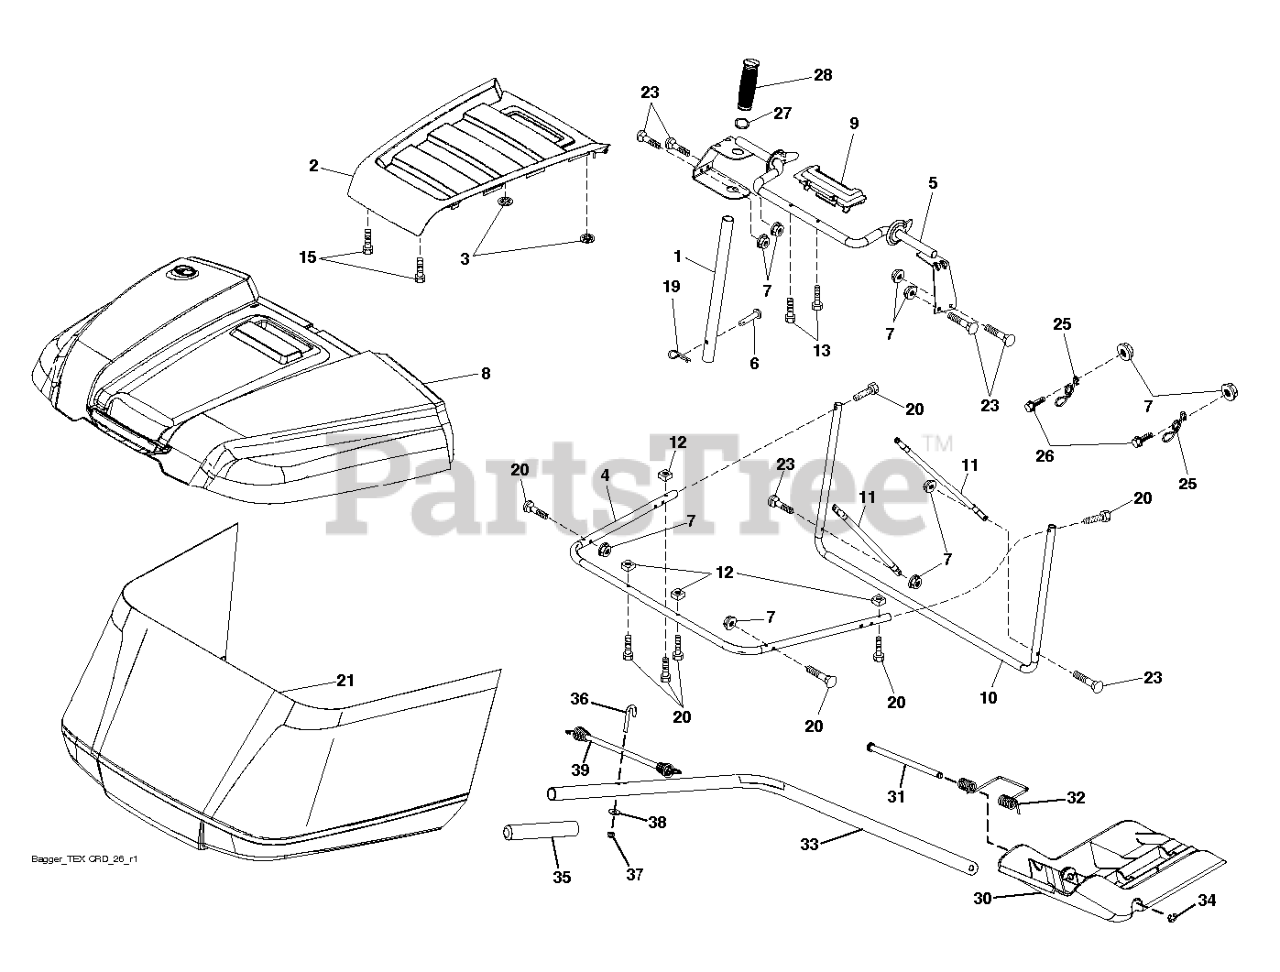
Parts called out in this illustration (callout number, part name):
1	TUBE.HANDLE.BAGGER.CRD/SRD.BLA
2	APPLIQUE.TOP.BAG.SRD.ORANGE
3	NUT.PUSH.156
4	SUBASM.TOP.TUBE.TEX.CRD
5	FRAME.ASM.TOP.BAGGER.SRD
6	RIVET,DRILLED
7	NUT T
8	BAGGER.TOP.SRD.APPLIQUE
9	INSERT.HANDLE.BAGGER.(2 2)
10	FRAME FRAME.FRONT.TEX.CRD
11	BRACE BRACE SIDE TUBE
12	NUT.SQUARE.1/4
13	SCREW.1/4X1.150.HXWSH
14	BOLT.SHOULDER.HX.WSH.1/4X1.150
15	SCREW,#8.FLAT.HEAD.DRILL.TIP
19	PIN.COTTER.5/16.BOW TI
21	BAG SUBASM. TEX CRD GEN 2 HUSQ
25	SPRING.LATCH.BAGGER.SRD
26	SCREW HEX CRT
27	RB GROMMET.RUBBER.SRD
28	GRIP.HANDLE.BLACK
30	PLUG PLUG
31	PIN PIN.HINGE
32	SPRING SPRING DOUBLE TORSION
33	SHAFT SHAFT TEX CRD MULCH PLU
34	E-RING.5/16"
35	GRIP GRIP MULCH PLUG HAND
36	BOLT BOLT J
39	BUBGEE BUBGEE TEX CRD
